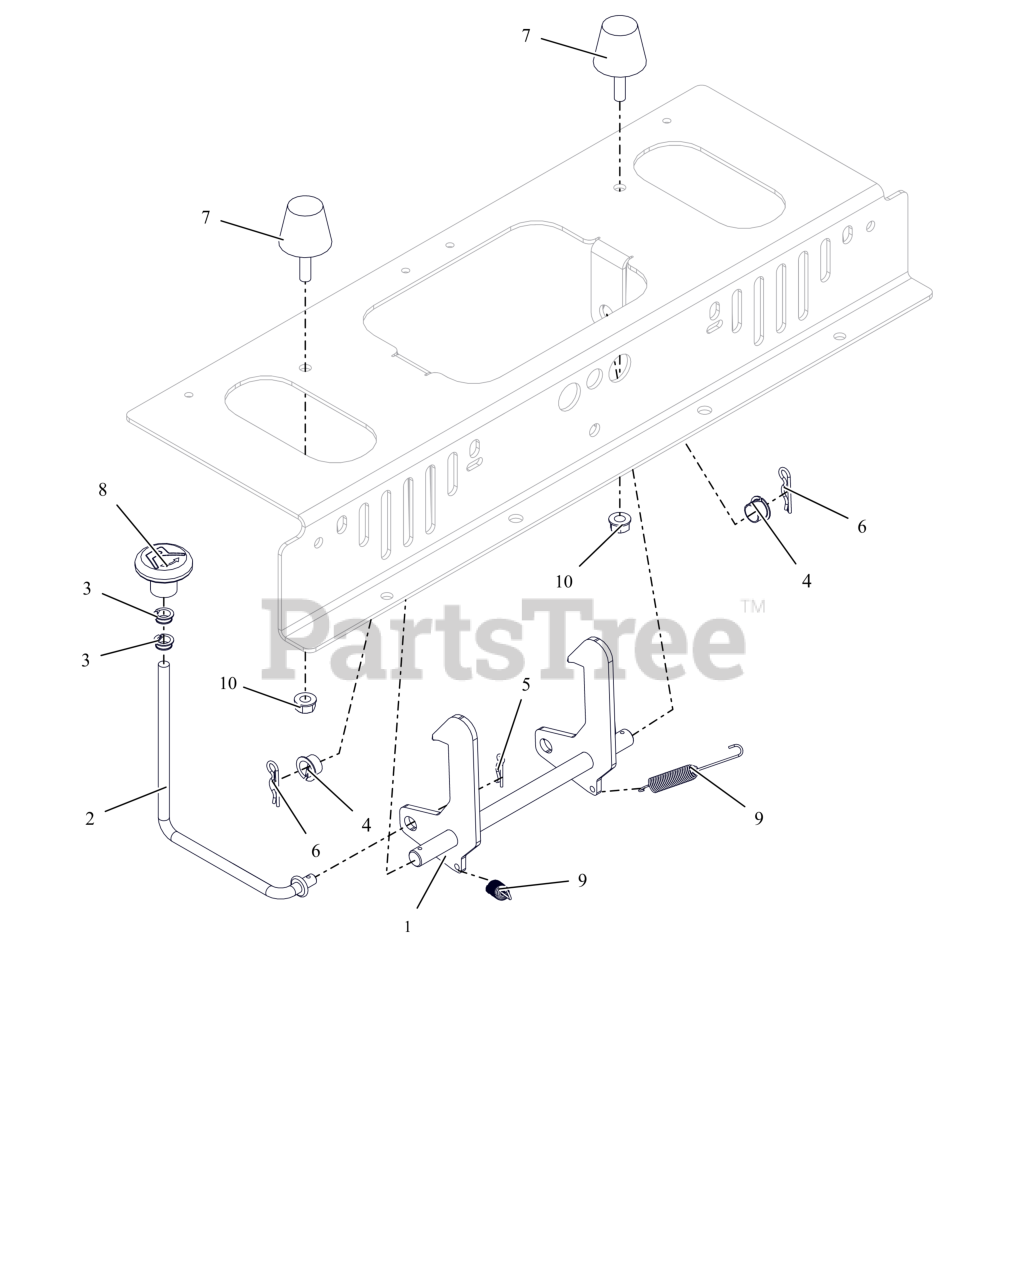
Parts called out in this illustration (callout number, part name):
1	SEAT LATCH WLDMT - LOW FILM
2	LINKAGE, SEAT RELEASE
3	BUSHING, POLYLINER-.38 SNAPIN
4	BUSHING, POLYLINER-.50 SPLIT
5	PIN, HAIR #225 .072X1.09
6	PIN, HAIR-INT .08X.38X1.42 ZCC
7	BUMPER,STUD MOUNTED CONE SHAPE
8	KNOB, PUSH/PULL
9	SG-TENS .043X.44X3.31 WLD 5.8
10	NUT,SPNLK-FLG .31-18 G5 ZCC
